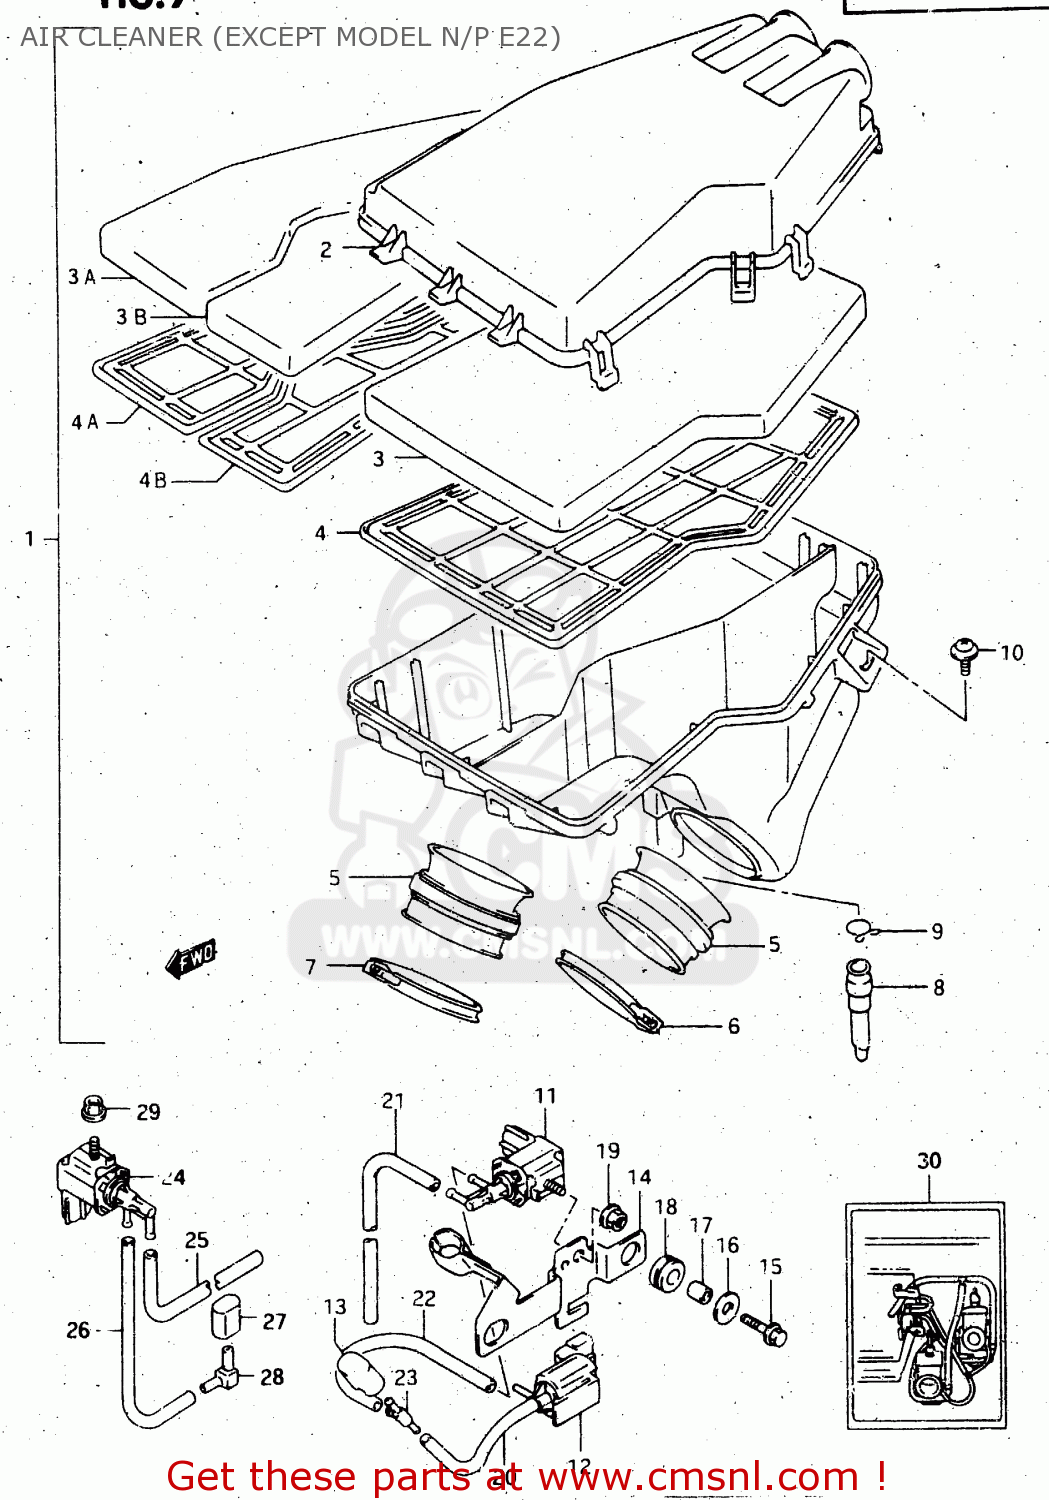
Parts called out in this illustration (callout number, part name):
1	CLEANER ASSY, AIR
2	CAP,AIR CLEANE
3	FILTER
3A	FILTER,AIR,R
3B	FILTER,AIR,L
4	HOLDER,FILTER
4A	HOLDER,FILTER,R
4B	HOLDER,FILTER,L
5	TUBE,OUTLET
6	CLAMP
7	CLAMP
8	DRAIN TUBE
9	CLIP
10	SCREW(6X16)
11	VALVE ASSY,MAIN AIR SOLENOID
12	VALVE,PILOT AIR
13	FILTER,SOLENOID VALVE
14	BRACKET, SOLENOID VALVE
15	BOLT
16	WASHER
17	SPACER(9.2X9X6.5)
18	CUSHION
19	NUT
20	HOSE
21	HOSE(4X7X600)
22	HOSE,MAIN AIR SOLENOID
23	3-WAY
24	VALVE ASSY,MAIN AIR SOLENOID
25	HOSE(4X7X600)
26	HOSE(4X7X600)
27	FILTER,SOLENOID VALVE
28	UNION
29	NUT
30	LABEL, CARBURETOR WARNING
